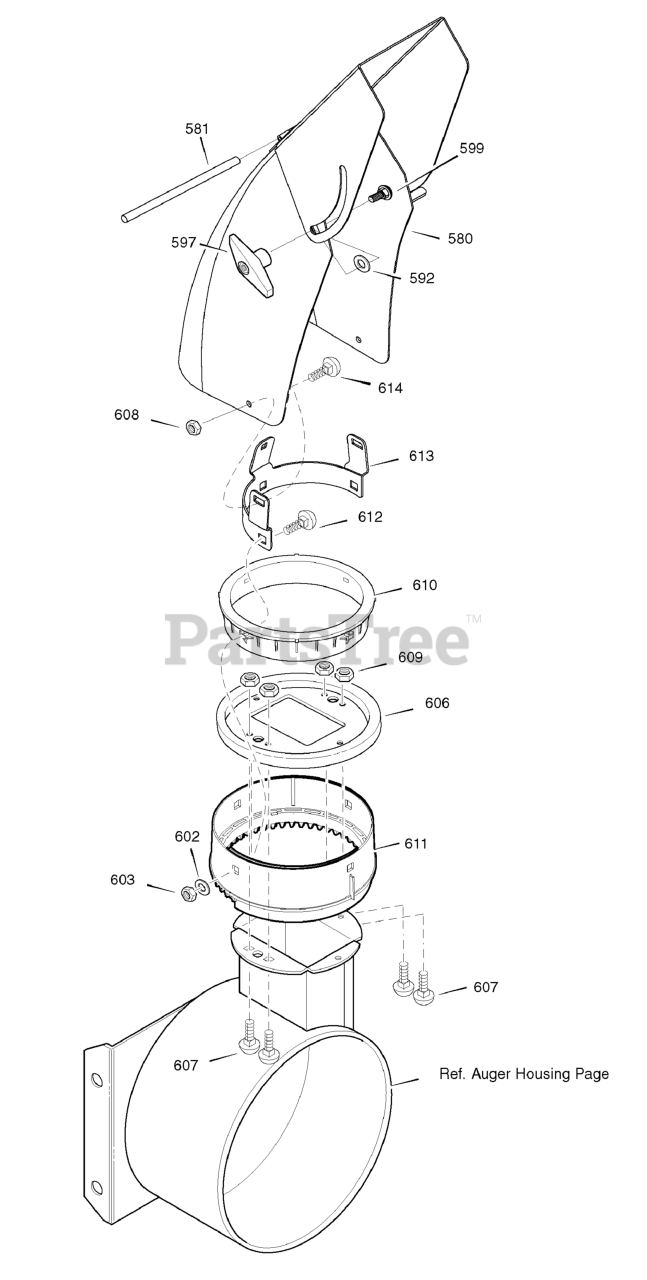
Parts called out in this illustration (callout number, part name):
580	DISCHARGE CHUTE
592	WASHER, PLASTIC
597	KNOB, T 3.00
599	BOLT, 5/16-18 X 1.50
602	WASHER, FLAT
603	NUT, 5/16-18 HEXNYL
606	CHUTE COLLAR
607	SCREW, 1/4-20 X 0.75
608	NUT, Hex Flange, 1/4-20
609	NUT, Nylock Flanged, 1/4-20
610	RETAINER RING INNER
611	RETAINER RING OUTER
612	BOLT, 5/16-18 X 1.00
613	ADAPTER, Chute Ring
614	CARRIAGE BOLT, 1/4-20 x 3/4, G5
